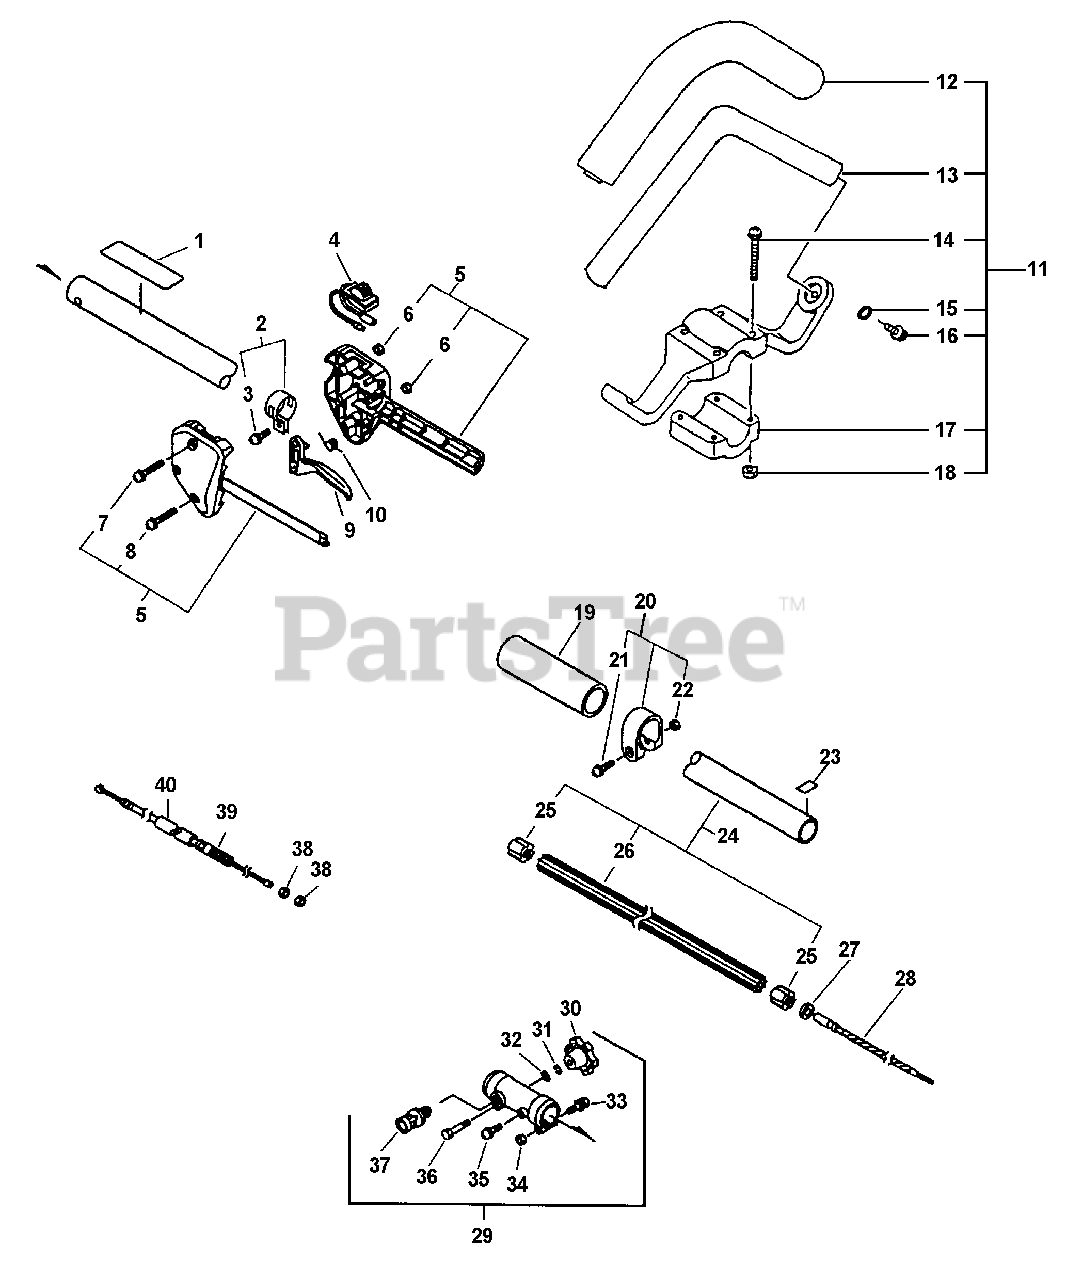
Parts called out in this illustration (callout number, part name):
1	LABEL - CAUTION -- SPANISH
2	CLAMP KIT
3	SCREW - 5X14
4	IGNITION SWITCH ASSY
5	CONTROL HANDLE KIT
7	SCREW - 5X35
8	SCREW - 5X25
9	TRIGGER, THROTTLE
10	SPRING, TRIGGER
11	HANDLE ASSY - FRONT
12	GRIP, HANDLE
13	HANDLE - FRONT
14	SCREW - 5X35
15	WASHER - 5
16	SCREW - 5X20
17	BRACKET, HANDLE - LOWER
19	GRIP, HANDLE
20	CLAMP KIT
21	SCREW - 5X28
23	LABEL - ALIGNMENT
24	MAIN PIPE ASSY
26	LINER - FLEXIBLE
28	DRIVESHAFT - FLEXIBLE -- UPPER
29	COUPLER ASSY
30	KNOB, FASTENER
31	LOCKWASHER - 5
32	WASHER - 5
33	SCREW - 5X30
35	SCREW - 5X12
36	BOLT - 5X35
37	LATCH ASSY
39	CABLE, THROTTLE
40	TUBE
